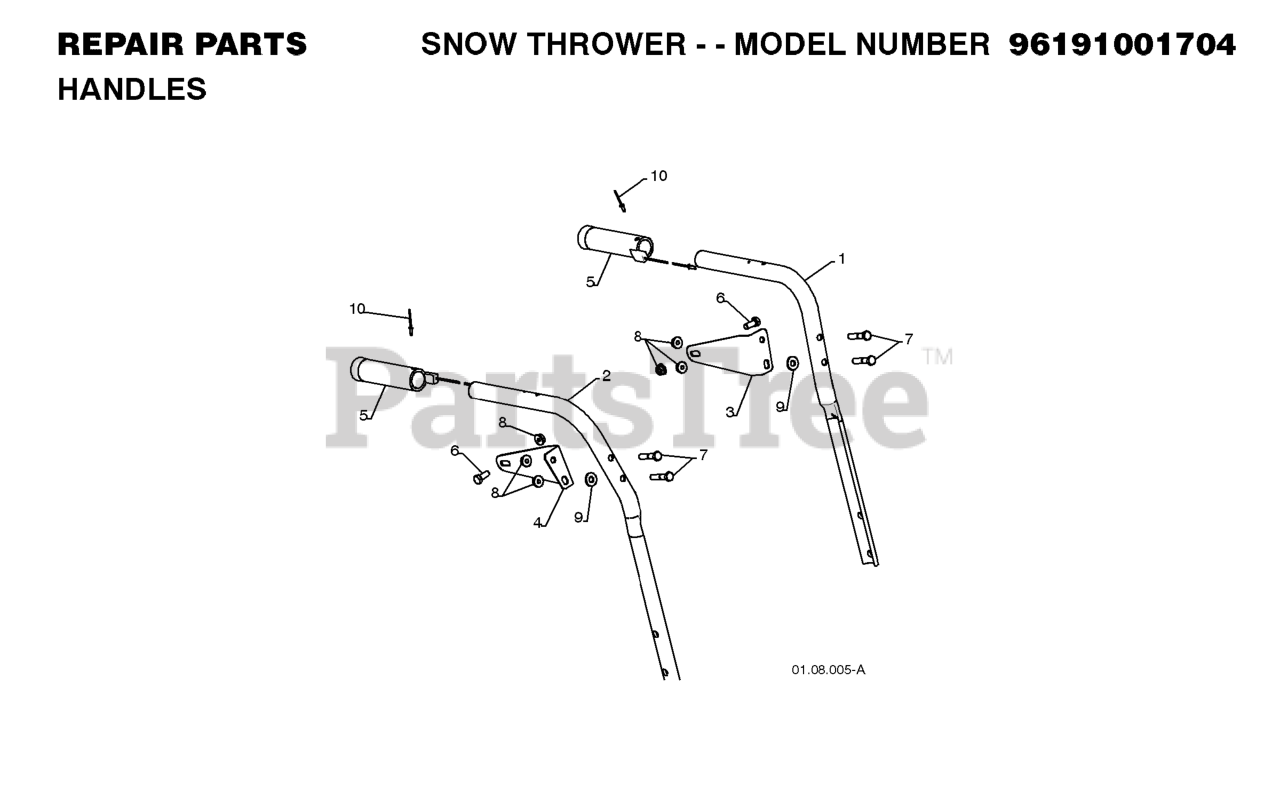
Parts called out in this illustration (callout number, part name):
1	TUBE.HANDLE.PLOW.LH.BLACK
2	TUBE.HANDLE.PLOW.RH.BLACK
3	BRKT.PANEL.LH.INT
4	BRKT.PANEL.RH.INT
5	GRIP.HANDLE.HEATED
6	BOLT.FIN.HEX.5/16-18X3/4
7	HEX BOLT
8	NUT.LOCK.5/16-18
9	WASHER.20X8.5
10	RIVET.POP.1/8X
